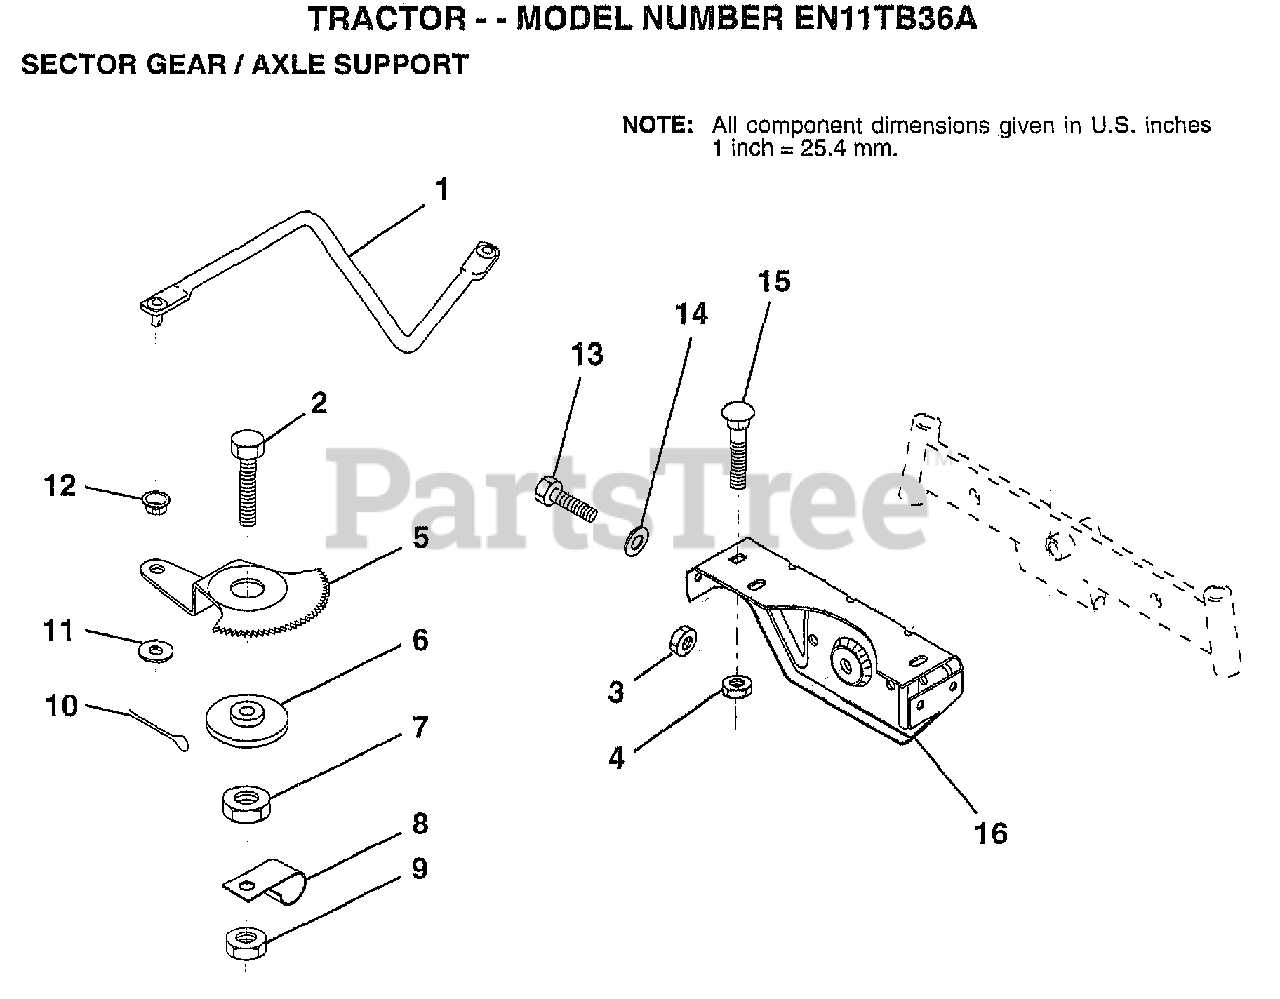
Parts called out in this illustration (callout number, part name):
1	DRAG LINK
2	"BOLT,HEX"
5	GEAR SECTOR
6	BUSHING
7	NUT
8	CLIP INSULATOR
9	NUT LTV
10	COTTER PIN
11	WASHER
12	BUSHING.DRAGLINK
13	BOLT
14	WASHER
15	BOLT
16	SUPT AXLE FRONT
